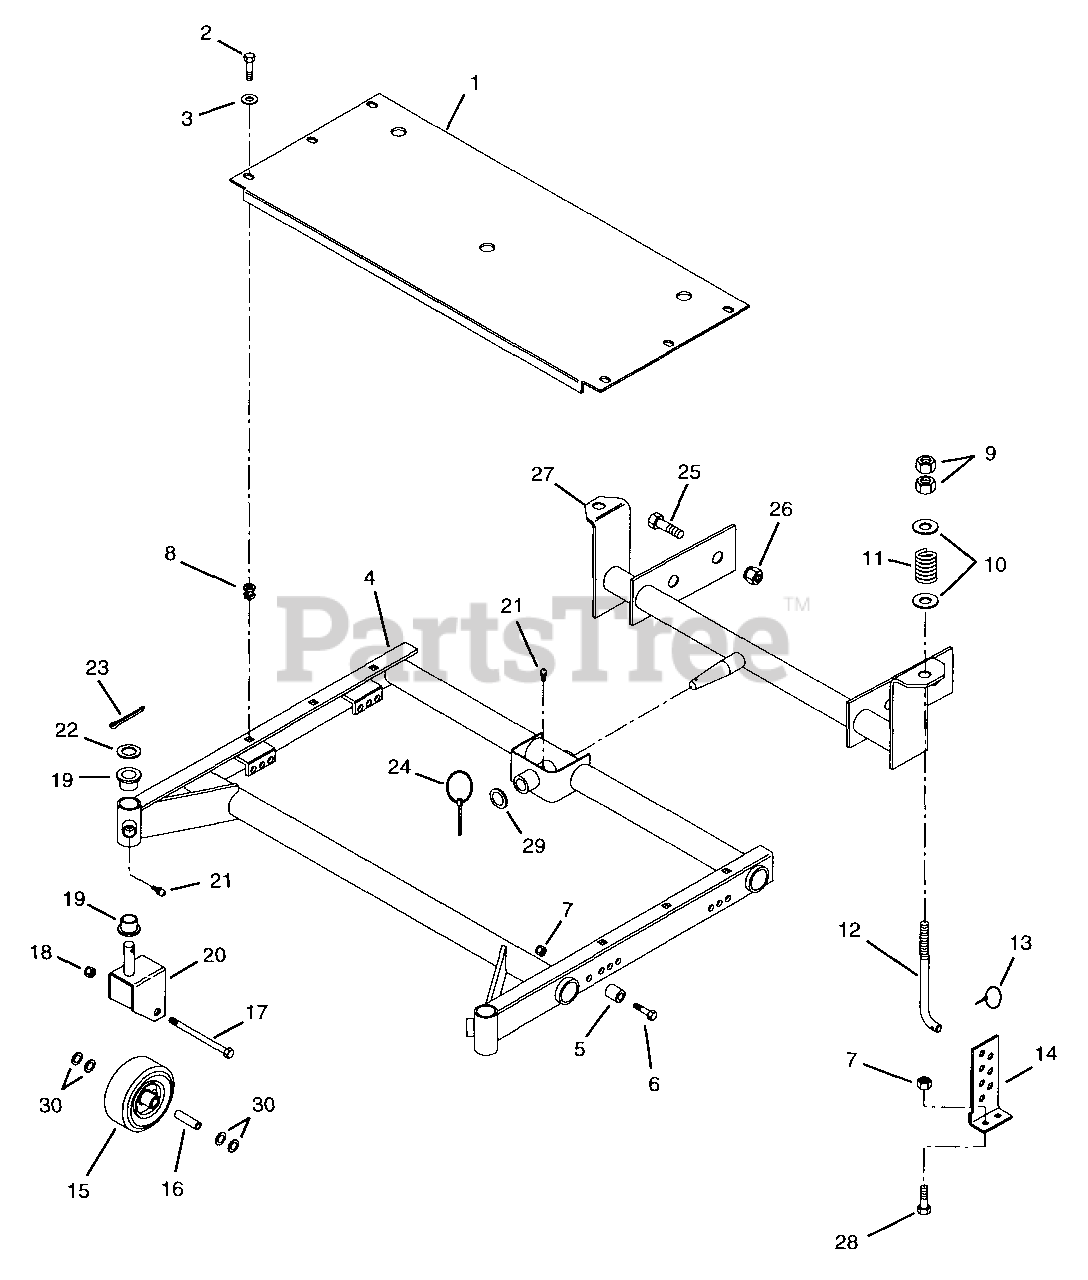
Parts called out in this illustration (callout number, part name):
1	Guard, 50" Mower Belt
2	Screw-Tapping, .25-20 x .50 Hex Slot Head
3	Washer-Flat-Steel .281 x .625 x .065
4	Weldment, Mower Frame
5	Bushing, .391 x .626 x .670
6	Bolt-Hex .38-16 x 1.50 Grade 5
7	Nut-Locking-Nylon .375-16 w/ Insr Grade 2
8	Grommet, Plastic
9	Nut .50-13
10	Washer-Flat-Steel .531 x 1.062 x .095
11	Spring-Compression.125 x 1.00 338 lbs/in
12	Rod, Height Adjuster
13	Pin-Klik 1.000 x .188 x 1.25
14	Bracket, Rear Adjuster Left Hand
15	Wheel, Gauge 9 x 3.50
16	Spacer .532 x .748 x 3.34
17	Bolt-Hex .50-13 5.50
18	Nut-Locking-Nylon .50-13 Grade 5
19	Bushing-Flange 1.385 x .75 x 1.75
20	Weldment, Caster Fork
21	Fitting, Lube .25-28 x 2.56
22	Washer-Hardened Thrust 1.002 x 1.552 x .030
23	Pin-Cotter .188 x 1.50
24	Pin-Kilk .25 x 1.75
25	Bolt-Hex .62-11 x 1.50
26	Nut-Locking .625-11 Hex.w/Insr
27	Weldment, Mower Frame Mounting
28	Bolt-Round Head Square Neck .375-16 x .75 Grade 1
29	Bearing-Needle-Thrust .752 x 1.24 x .031
30	Washer-Flat-Steel .531 x 1.250 x .100
